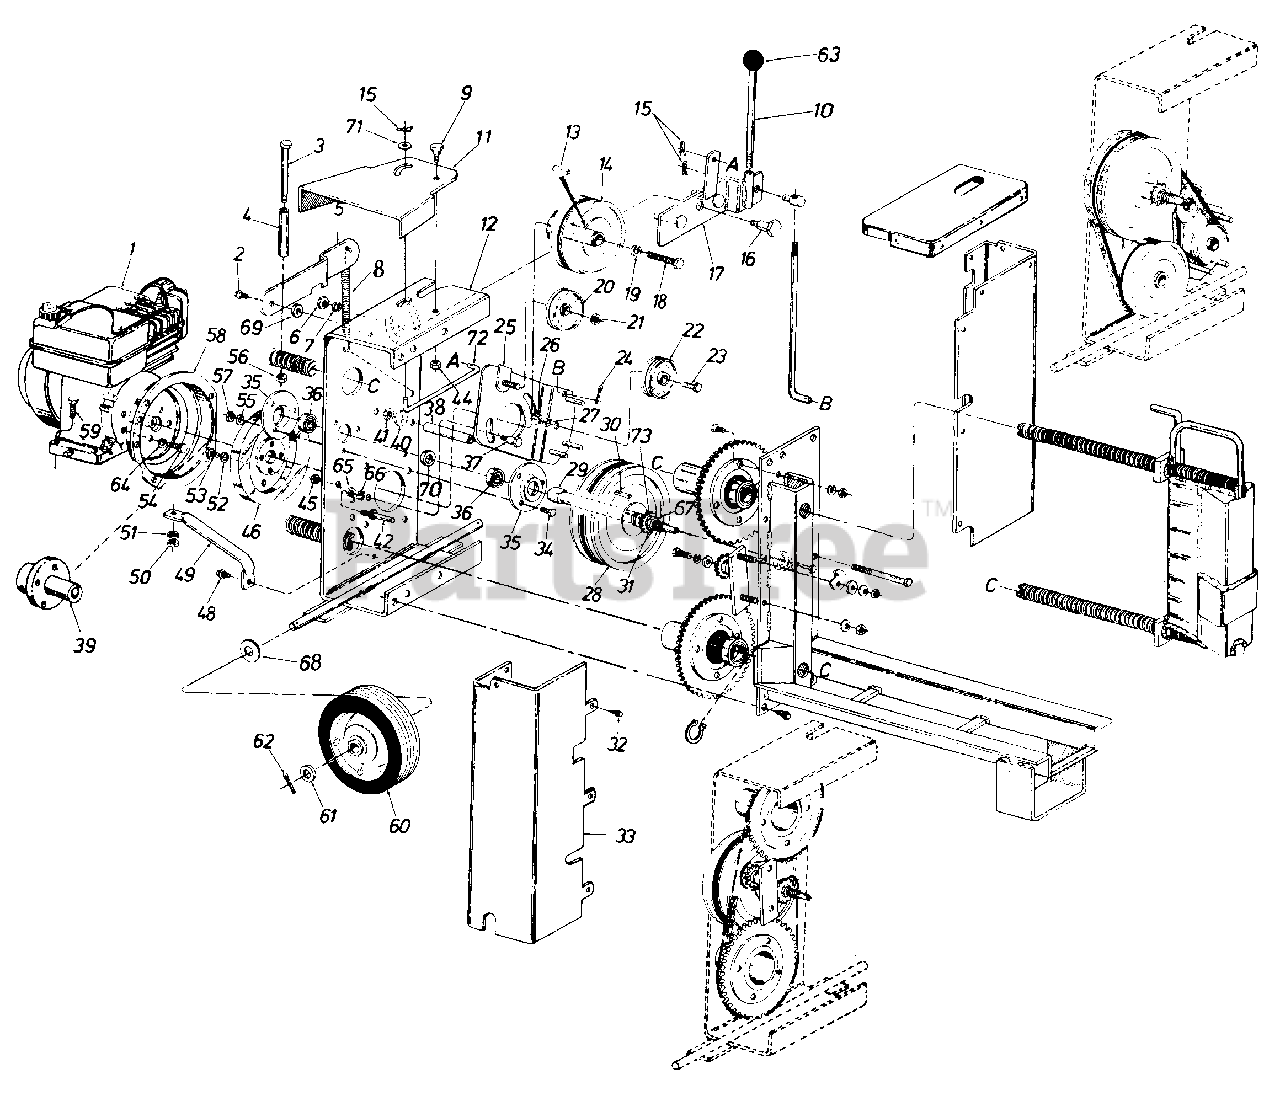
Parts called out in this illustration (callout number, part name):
1	Engine
2	Hex. Wash. SF Tapp Scr. 3/8" x 7/8" Lg.
3	Hex Bolt 3/8-16 x 4.5" Lg.
4	Spacer 3/8 I.D. x 5/8 O.D. x 2-5/8 Lg.
5	Spring Retainer Bracket
6	Hex Nut 3/8-16 Thd.*
7	L.-Wash. 3/8 I.D.*
8	Spring
9	Shld. Bolt
10	Engagement Handle
11	Lever Return Bracket
12	Motor Mounting Plate Ass'y.
13	Sq. Key 3/16 x 2.0" Lg.
14	Step Pulley
15	Internal Cotter Pin 1/8" Dia.
16	Shld. Bolt
17	Engagement Handle Brkt. Ass'y.
18	Hex Bolt 3/8-24 x 3.0 Lg.*
19	L.-Wash. 3/8 I.D.*
20	Idler Pulley
21	Hex Nut 3/8-16 Thd.*
22	Idler Pulley 2-3/4
23	Hex Bolt 3/8-16 x 1.5" Lg.*
24	Cotter Pin 1/8" Dia. x 3/4" Lg. *
25	Engagement Bracket Ass'y.
26	Hex Nut 3/8-16 Thd.*
27	L-Wash. 3/8" I.D.*
28	Engine Pulley
29	Jack Shaft Spindle
30	Sq. Key 3/16 x 2.0 Lg.*
31	Sprocket 12T #20 Chain
32	Hex. Wash. TT Tapp Scr. 3/8x 1/2" Lg.
33	Belt Cover R.H.
34	Hex Bolt 5/16-18 x .75" Lg.
35	Small Bearing Housing
36	Ball Bearing .787 I.D. x 1.85 O.D.
37	Shld. Bolt
38	Spacer .38 I.D. x 62 O.D. 4.5 Lg.
39	Fly Wheel Mtg. Hub
40	Fl.-Wash. 3/8 I.D. x 1.25 O.D. x .10
41	Hex Nut 3/8-16 Thd.*
42	Stud 1/4" x 2-7/8" Lg.
44	Hex Cent. L.-Nut 5/16-18 Thd.
45	Hex Nut 1/4-20 Thd.*
46	Flywheel
48	Hex Wash. SF Tapp Scr. 3/8 x 7/8
49	Engine Brace
50	Hex Nut 5/16-18 Thd.*
51	L.-Wash. 5/16 I.D.*
52	L.-Wash. 1/4" I.D.*
53	Socket Hd. Scr. 1/4-28 x 1.50" Lg. *
54	Hex Bolt 5/16-24 x 5/8" Lg.*
55	L.-Wash. 5/16 I.D.*
56	Hex Cent. L.-Nut 3/8-16 Thd.
57	Hex Nut 5/16-18 Thd.*
58	Motor Mount Cup
59	Hex Bolt 5/16-18 x 1.25" Lg. *
60	Wheel Ass'y. 10.0 x 2.75
61	Fl.-Wash. 5/8 I.D. x 93 O.D. x .06
62	CotterPin 1/8" x 1.0" Lg.*
63	Ball Knob
64	L.-Wash. 5/16 I.D.*
65	Hex Cent. L.-Nut 3/8-16 Thd.
66	Bell.-Wash.
67	Hex Jam Nut 5/8-18 Thd.
68	Fl.-Wash. .62" I.D. x 1.25"O.D.
69	Spacer .38" I.D. x .50" O.D. x.187" Lg.
70	Spacer.79" I.D. x 1.00" O.D. x.177" Lg.
71	Fl.-Wash. 5/16" I.D. x 3/8" O.D.
72	Rod Lever Return
73	L.-Wash. 5/8" I.D.*
